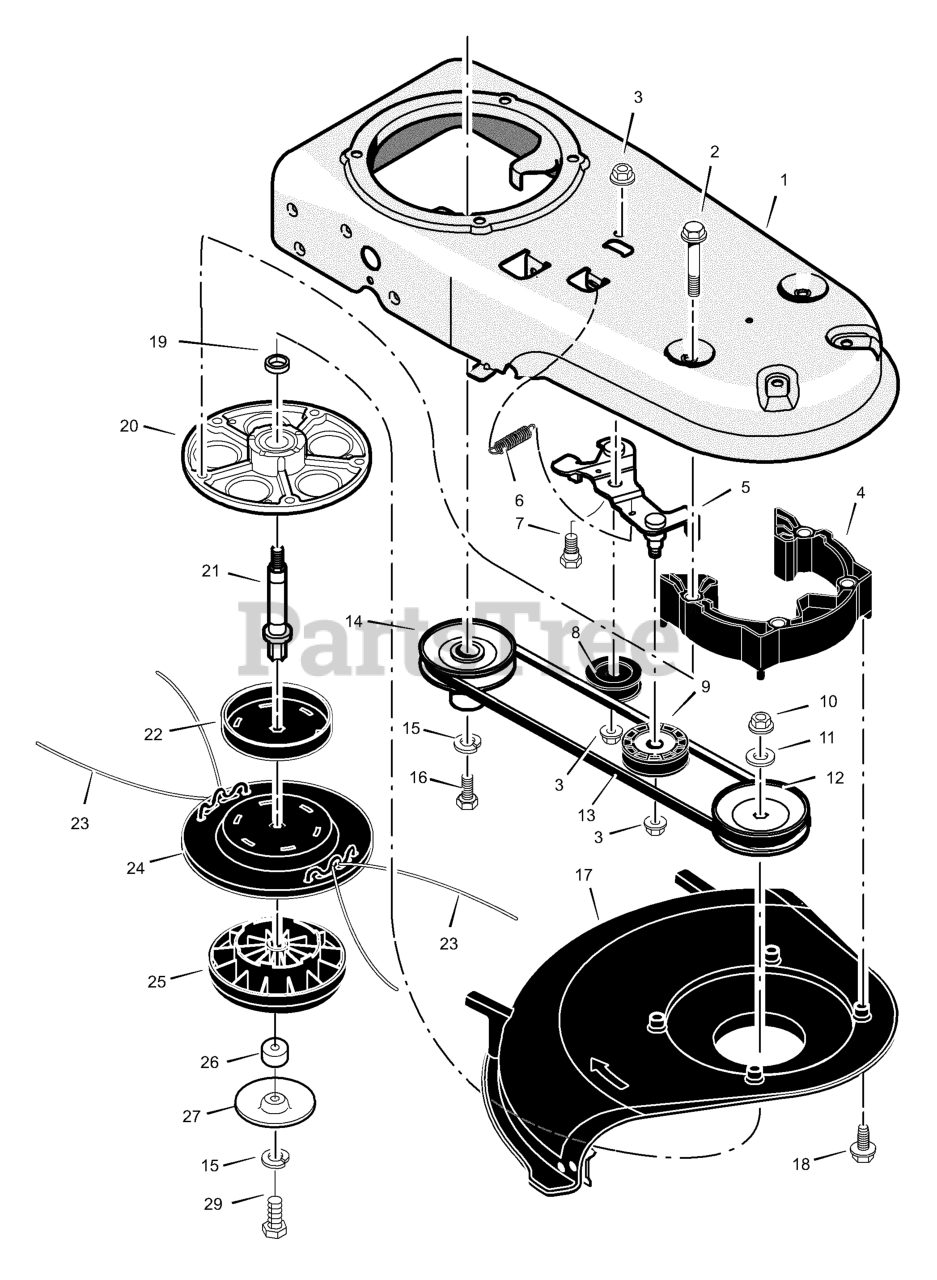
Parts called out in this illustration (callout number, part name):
1	Frame, Trimmer
3	Nut
4	Spacer Assembly, Jackshaft
5	Bracket, Idler Assembly
6	Spring
7	Bolt, Shoulder
8	Pulley, Idler
9	Pulley, "V"
11	Washer
12	Pulley, Cutting Head
14	Pulley, Drive
15	Lockwasher, Split
17	Shield, Trimmer
19	Spacer
20	Housing, Jackshaft
21	Jackshaft
22	Shield, Weed
23	Line, 0.130" x 16.75 (24 pack)
24	Head, Cutting
25	Guide, Height
27	Abrasion-Shield
